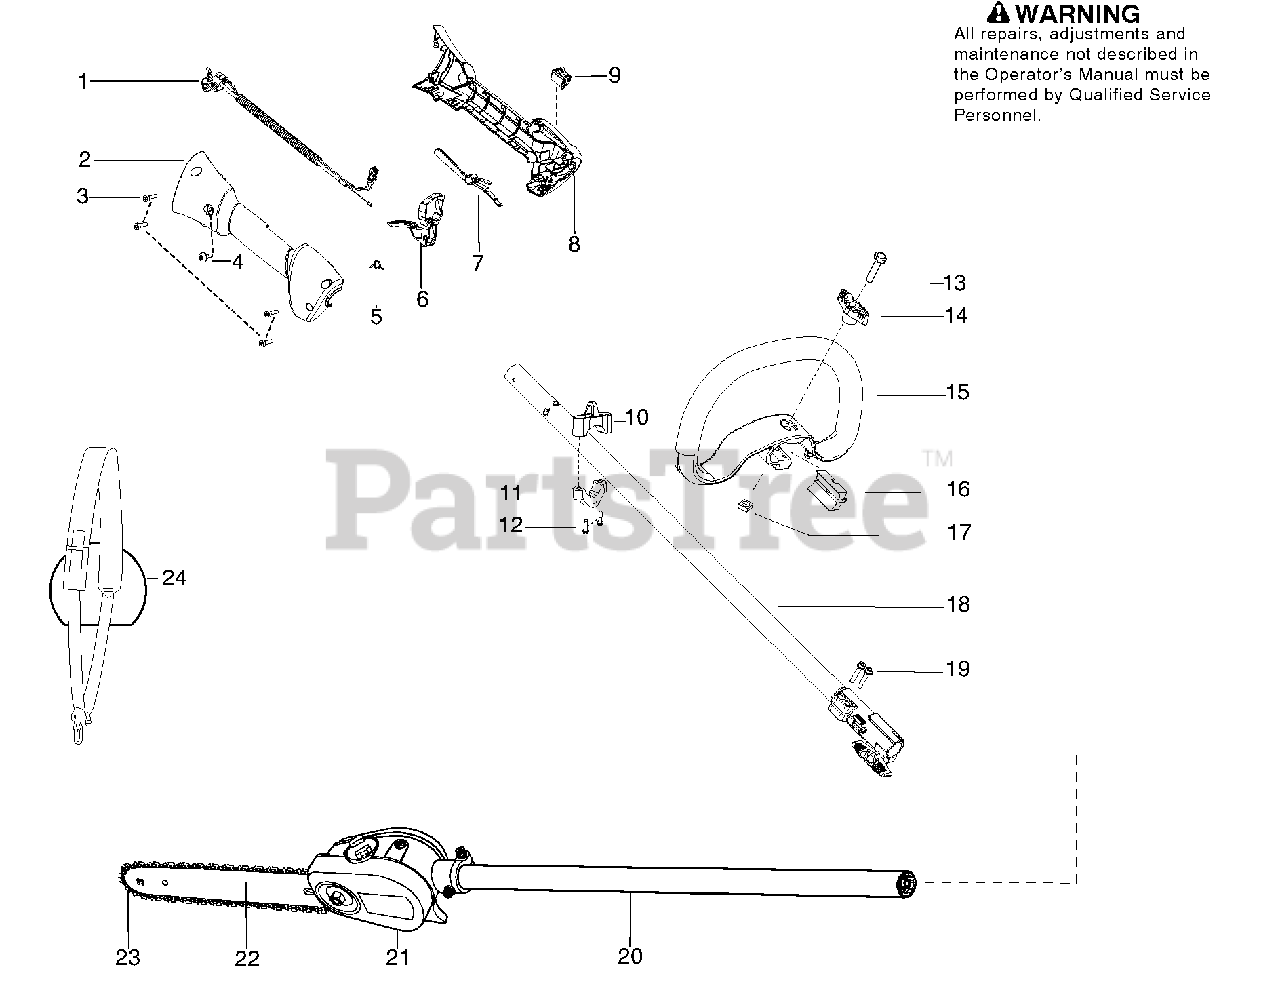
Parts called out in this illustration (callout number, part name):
1	Assy-Cable/Wire Harness
2	Housing-Throttle (RH)
5	Spring-Trigger
7	Lockout-Throttle
8	Housing-Throttle (LH)
9	Kit-Switch
10	Clamp - Upper Harness
11	Clamp - Lower Harness
15	Assy - Loop Handle
17	Nut - Square M6
18	Kit-Driveshaft Upper
20	Kit-Pruner Drive Shaft
21	Assy-Pruner Gearbox
22	Bar - 12"
23	Chain - 12"
24	Harness - Diagonal with sign
